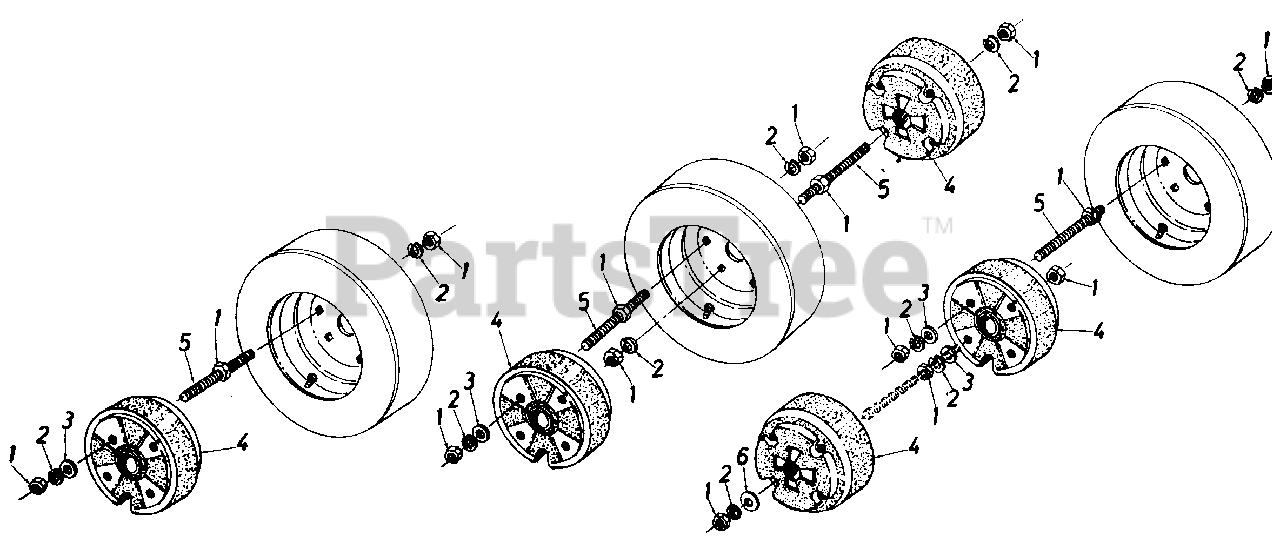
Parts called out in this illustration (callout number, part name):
1	Hex Nut 1/2-1 Thd.
2	Lock Washer 1/2" I.D.
3	FlatWasher .53" I.D. x.93" O.D.
4	Wheel Weight
5	Rod Threaded 1/2-13 x 9.50 Lg.
6	Fl.-Wash. .50" I.D. x 2.00" O.D.
